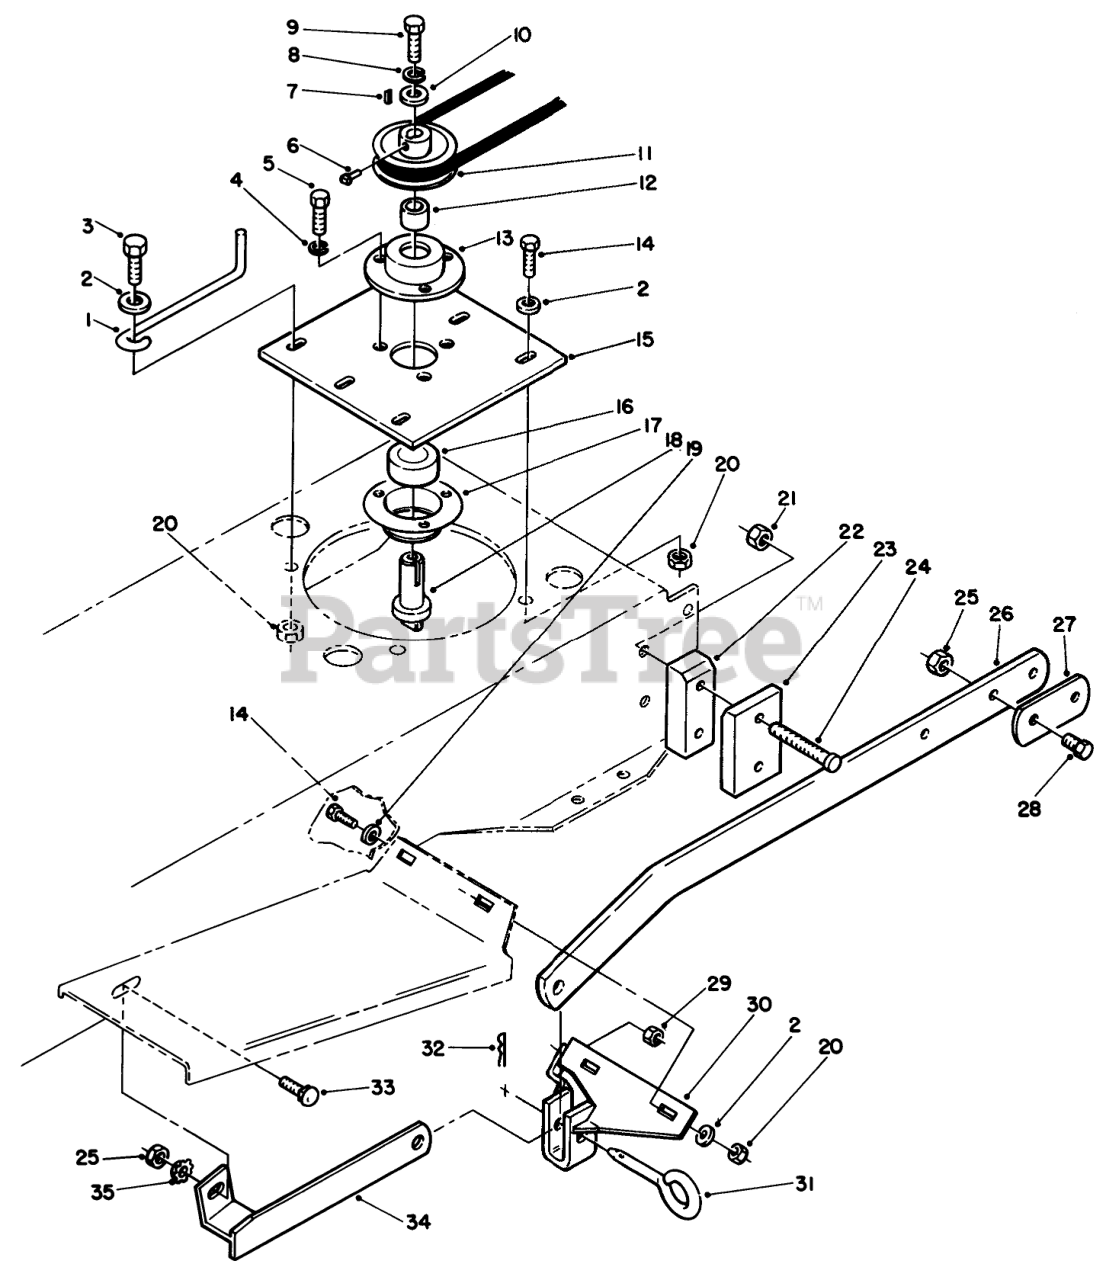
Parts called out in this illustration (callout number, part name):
1	GUIDE-BELT
2	WASHER-PLAIN
3	SCREW-HH
4	WASHER-LOCK
5	SCREW-HH
6	SCREW-SQH
7	KEY
8	WASHER-LOCK
9	SCREW-HH
10	WASHER
11	PULLEY
12	SPACER SHAFT
13	BEARING-CUP
14	SCREW-HH
15	PLATE-MTG R
16	BEARING-BALL
17	BEARING-CUP W/NUTS
18	SHAFT-DRIVE
19	WASHER-SPECIAL
20	NUT-LOCK, NI
21	NUT-LOCK, NI
22	SPACER-RUB BLOCK R
23	Block Rubber
24	Screw-Pan Hd.
25	NUT-LOCK, NI
26	Bar-Pivot
27	SPACER R
28	SCREW-HH
29	Nut
30	ASS'Y-BRACKET LH R
31	PIN-TOOL
32	Hairpin Cotter
33	BOLT-CARR
34	WELDMENT-BRACE L. R
35	WASHER
